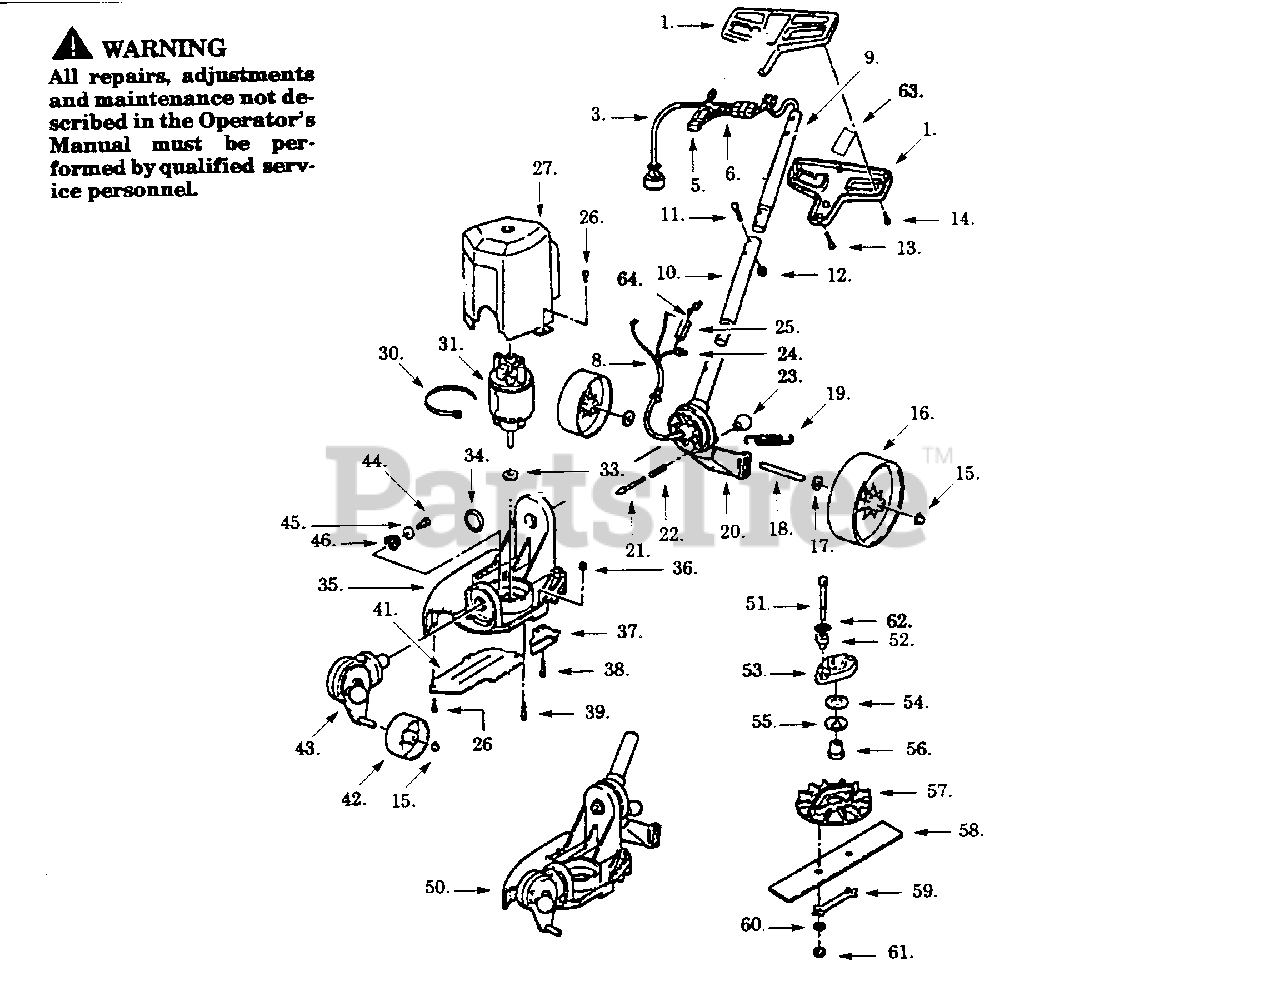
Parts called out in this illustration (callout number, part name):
1	Handle Set
3	Power Cord
6	P.C. Board Ass'y.
8	Harness Ass'y.
9	Upper Tube
10	Lower Tube
15	Push Nut
16	Rear Wheel
18	Rear Axle
20	Rear Swivel
21	Swivel Lock Shaft
22	Swivel Lock Spring
24	Terminal Cap
25	Resister
27	Motor Cover
30	Tie Wrap
31	Motor Ass'y.
34	Retaining Ring
35	Deck Frame
37	Blade Guide
41	Side Guard Plate
42	Front Wheel
43	Front Swivel Ass'y.
46	Front Swivel Spring
50	Edger Frame Ass'y.
52	Insulating Sleeve
53	Clutch Plate
55	Spring Washer
56	Clutch Sleeve
59	Lock Strap
60	Lockwasher
